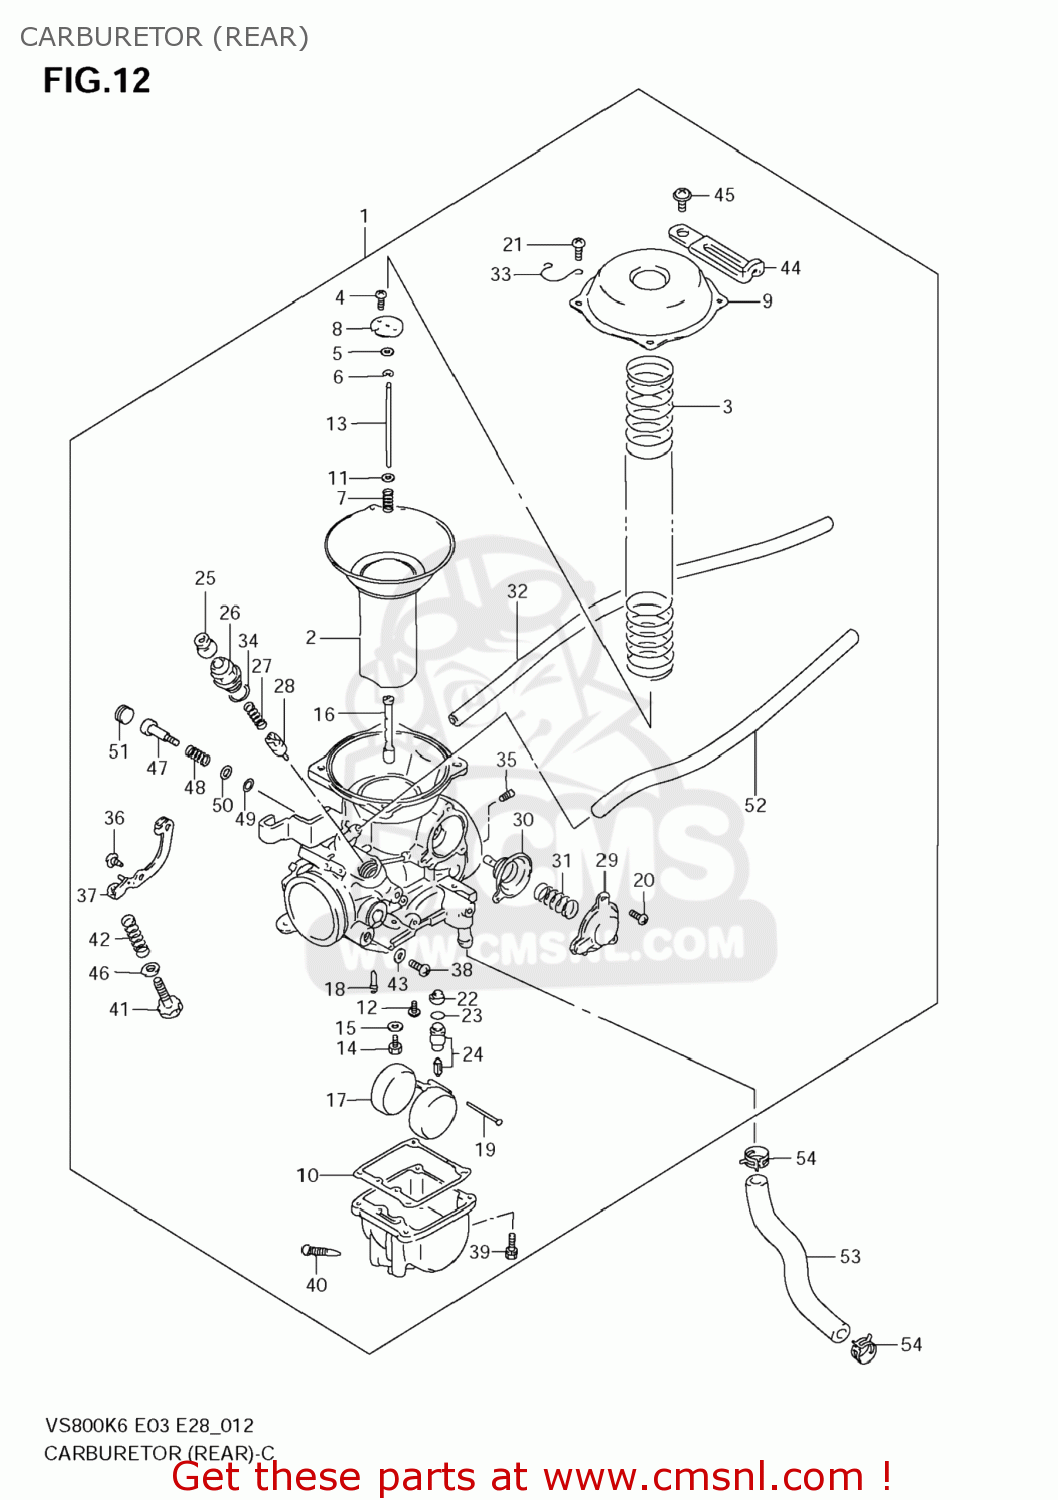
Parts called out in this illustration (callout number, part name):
1	CARBURETOR ASSY,RR
2	DIAPHRAGM,CARBURETOR
3	SPRING,DIAPHRAGM
4	SCREW
5	RING
6	CLIP
7	SPRING
8	PLATE
9	COVER
10	GASKET,FLOAT CHAMBER (NAS)
11	WASHER
12	JET,PILOT(45)
13	NEEDLE,JET
14	JET,MAIN(132.5)
15	WASHER
16	JET,NEEDLE(P-7M)
17	FLOAT
18	SCREW
19	PIN,FLOAT
20	SCREW
21	SCREW
22	FILTER
23	O RING,NEEDLE VALVE SEAT
24	VALVE ASSY,NEEDLE
25	CAP
26	HOLDER,GUIDE
27	SPRING
28	PLUNGER,STARTER
29	COVER
30	DIAPHRAGM ASSY
31	SPRING
32	HOSE(5X8.2X600)
33	CLIP
34	O RING
35	JET,AIR(65)
36	SCREW
37	LEVER ASSY
38	SCREW
39	SCREW
40	SCREW,DRAIN
41	ADJUSTER
42	SPRING
43	GASKET,DRAIN PLUG (NAS)
44	CLAMP(L:80)
45	SCREW
46	WASHER
47	SCREW,PILOT
48	SPRING
49	O RING,PILOT AIR SCREW
50	WASHER
51	PLUG
52	HOSE ASSY
53	HOSE
54	CLIP
